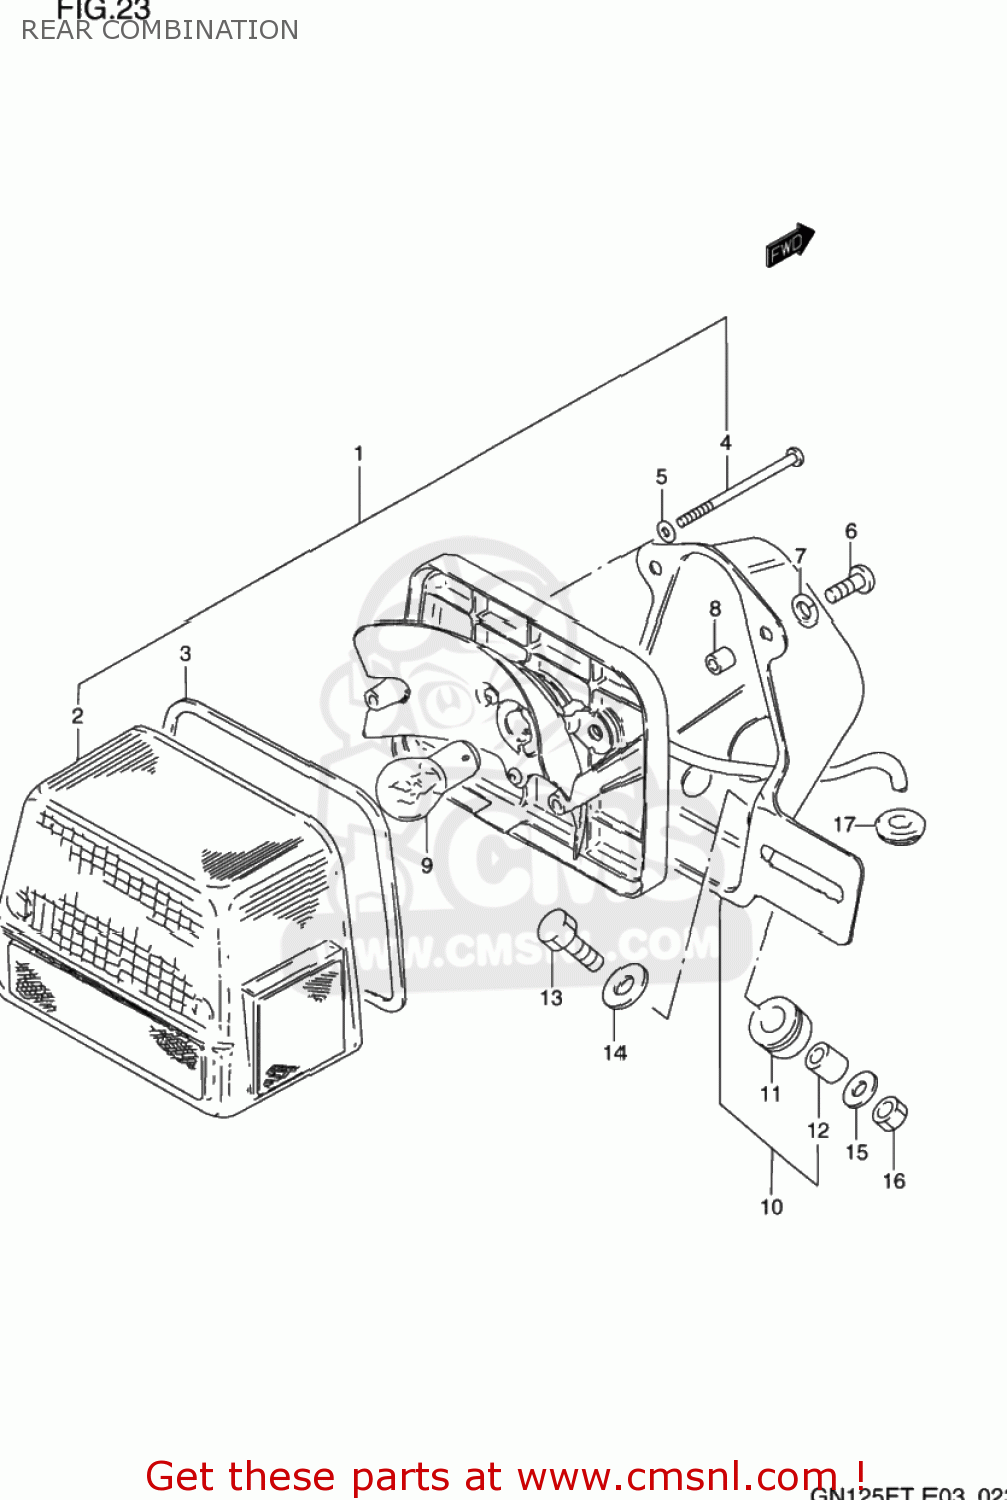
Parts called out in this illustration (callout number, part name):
1	LAMP UNIT,RR COMBNATION
2	LENS
3	GASKET (NAS)
4	SCREW
5	GASKET (NAS)
6	SCREW
7	LOCK WASHER
8	SPACER
9	BULB(12V23W)
10	BRACKET UNIT,TAIL LAMP
11	CUSHION
12	SPACER
13	BOLT(6X25)
14	WASHER (6.5X20X1.2)
15	WASHER
16	NUT
17	GROMMET
